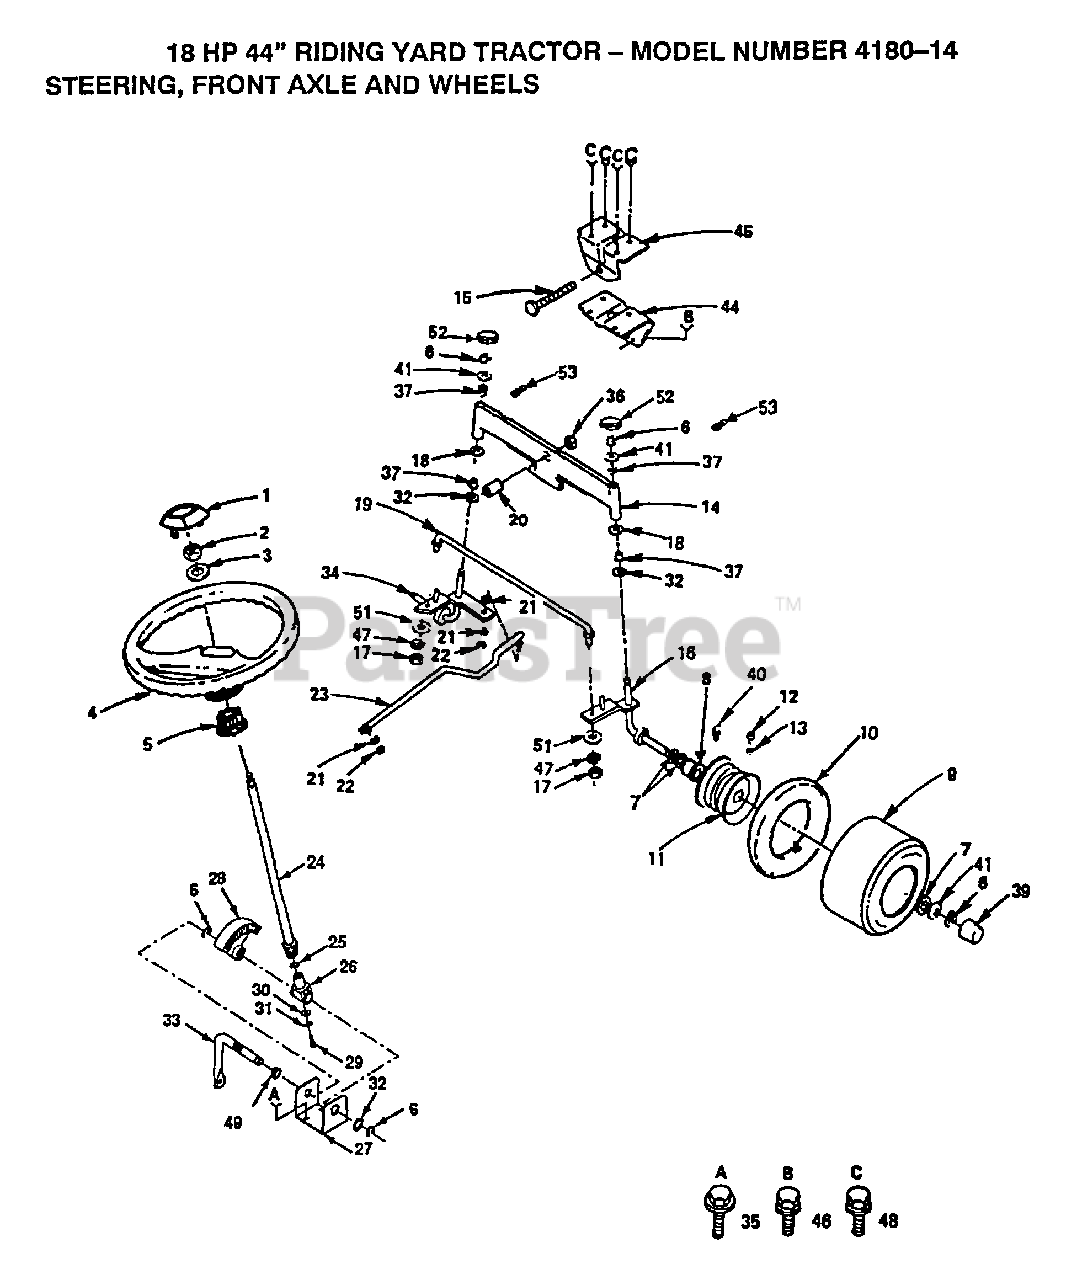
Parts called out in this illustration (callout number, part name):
1	"INSERT,STR WHEEL"
3	WASHER
5	ADAPTER LT
6	RING
7	WASHER
8	"FLANGE, BEARING"
10	TUBE.5.3/4.5/6
12	VALVE STEM LT
13	VALVE CAP
14	FRONT AXLE
15	BOLT LT
17	NUT.LOCK.5/16-24
18	WASHER
19	ROD TIE
20	BEARING
21	LOCKWASHER
25	THRUST WASHER
26	SUPPORT.SHAFT
27	"BRKT,STEERING"
29	"SCREW,SPECIAL"
31	LOCKWASHER
34	SPINDLE-LH LT
35	SCREW
37	COL. SRTG. BEAR.
39	HUB CAP
40	FITTING LT
41	WASHER
44	SUPPORT.SADDLE.FT
45	SUPPORT-SADDL T
46	SCREW LT
47	LOCKWASHER
48	SCREW SPECIAL
49	NYLINER T
51	WASHER M
52	CAP
53	ZERK M
62	WASHER .T
